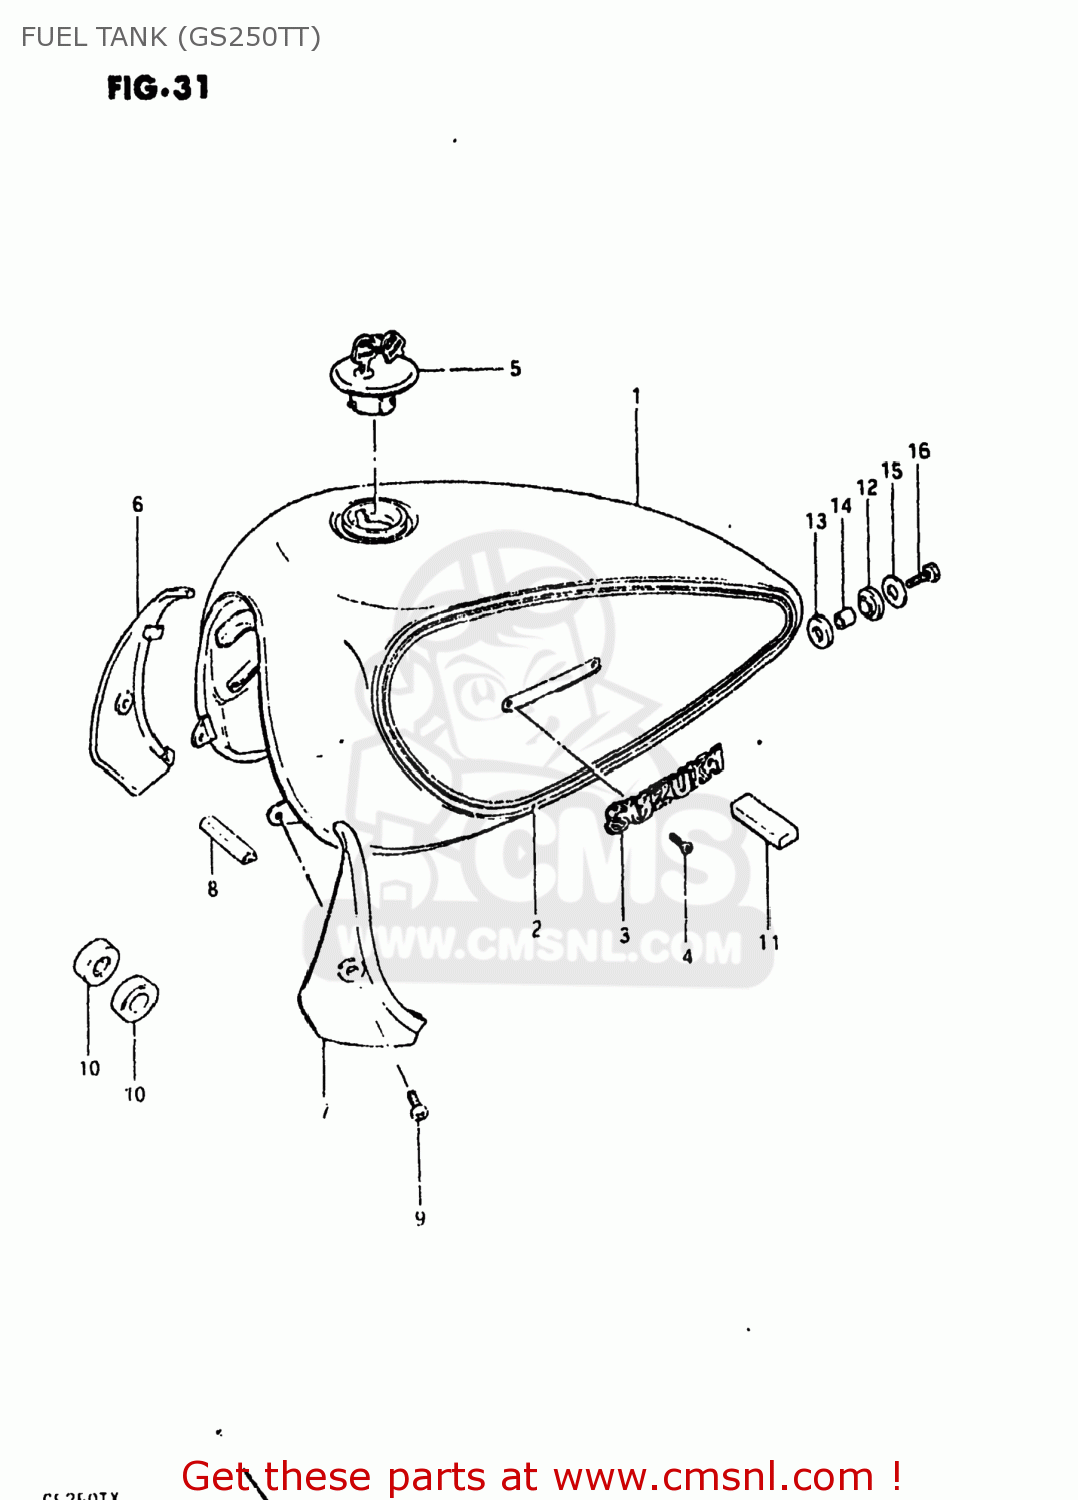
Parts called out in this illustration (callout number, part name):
1	TANK ASSEMBLY,FUEL
2	TAPE SET,FUEL TANK
3	EMBLEM,FUEL TANK
4	SCREW 3X6
5	CAP SET,FUEL TANK
6	COVER,FUEL TANK,FRONT,RIGHT
7	COVER,FUEL TANK,FRONT,LEFT
8	TUBE, FRONT
9	SCREW 6X12
10	CUSHION
11	CUSHION
12	CUSHION
13	CUSHION
14	SPACER(8.5X12X19)
15	WASHER (8.5X29X1.6)
16	BOLT (8X30)
